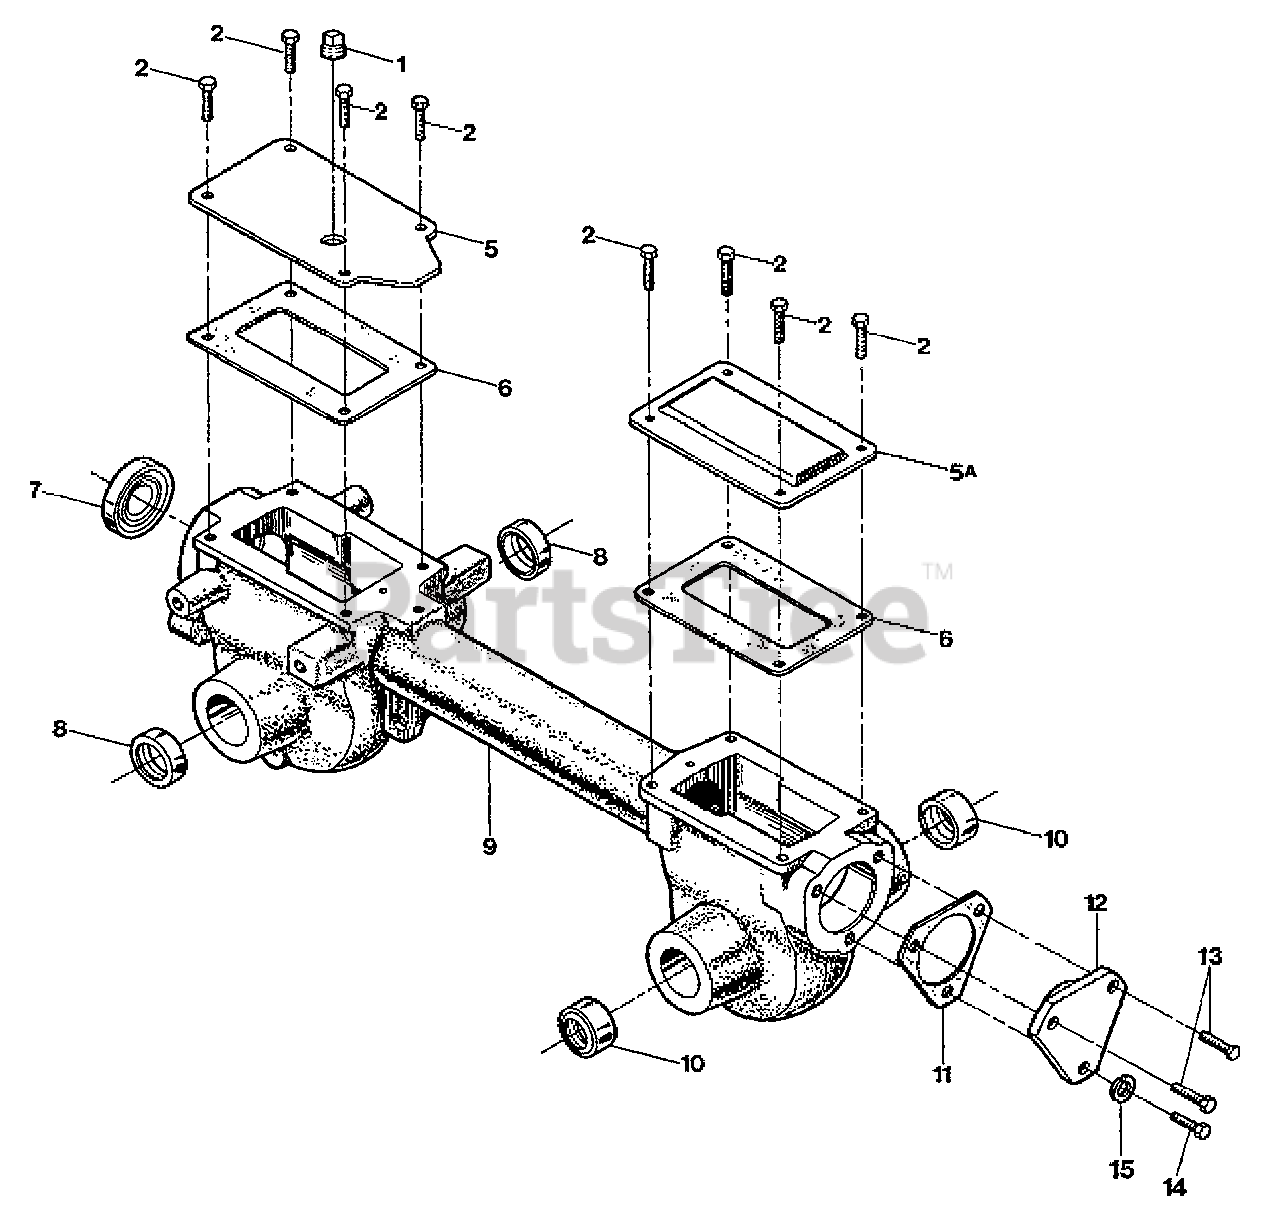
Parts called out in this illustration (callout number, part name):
1	Plug, Transmission Oil Fill
2	Flange Screw, Grade 5, 5/16-18 x 5/8
5	Front Cover, Transmission
5A	Rear Cover, Transmission
6	Gasket, Housing Cover
7	Oil Seal, Drive Shaft
8	Oil Seal, Wheel Shaft
9	Transmission Housing Assembly
10	Oil Seal, Tine Shaft
11	Gasket, Bearing Cap (.010" thick)
12	Rear Bearing Cap
13	Flange Screw, 5/16-18 x 1
14	Flange Screw, 5/16-18 x 3/4
15	Lockwasher, 5/16
